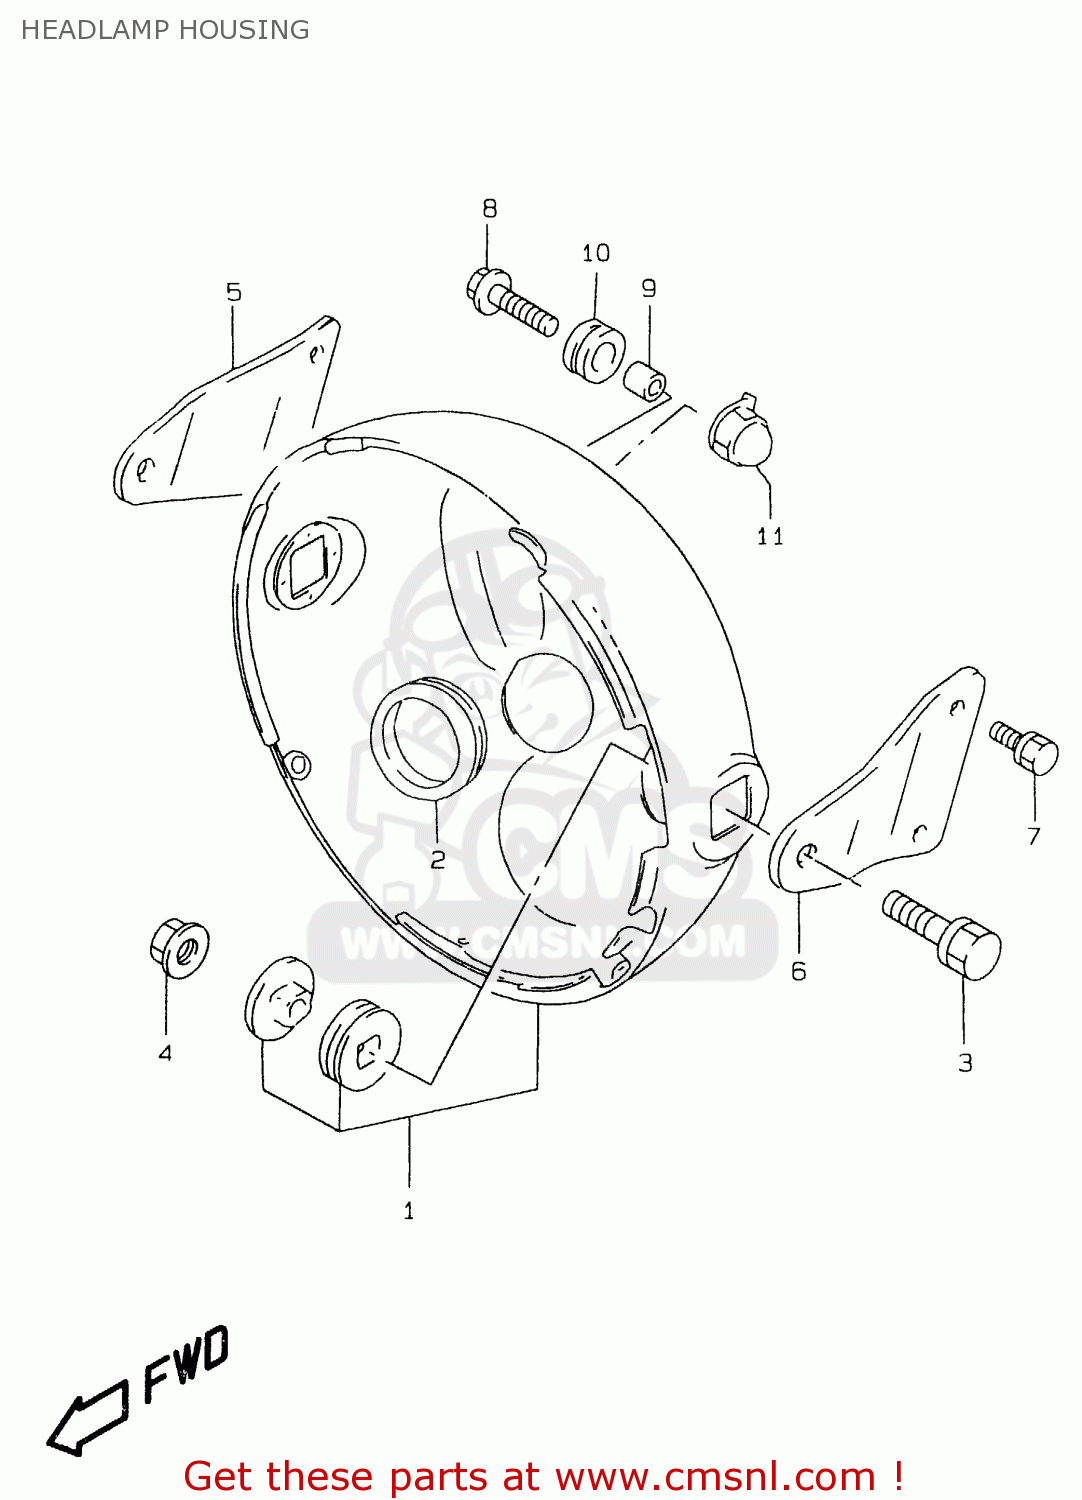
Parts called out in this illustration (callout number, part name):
1	HOUSING,HEADLAMP
2	GROMMET
3	BOLT
4	NUT
5	STAY,HEADLAMP HOUSING,R
6	STAY,HEADLAMP HOUSING,L
7	BOLT
8	BOLT
9	SPACER(6.5X10.5X12)
10	CUSHION
11	PLATE,HEADLAMP
